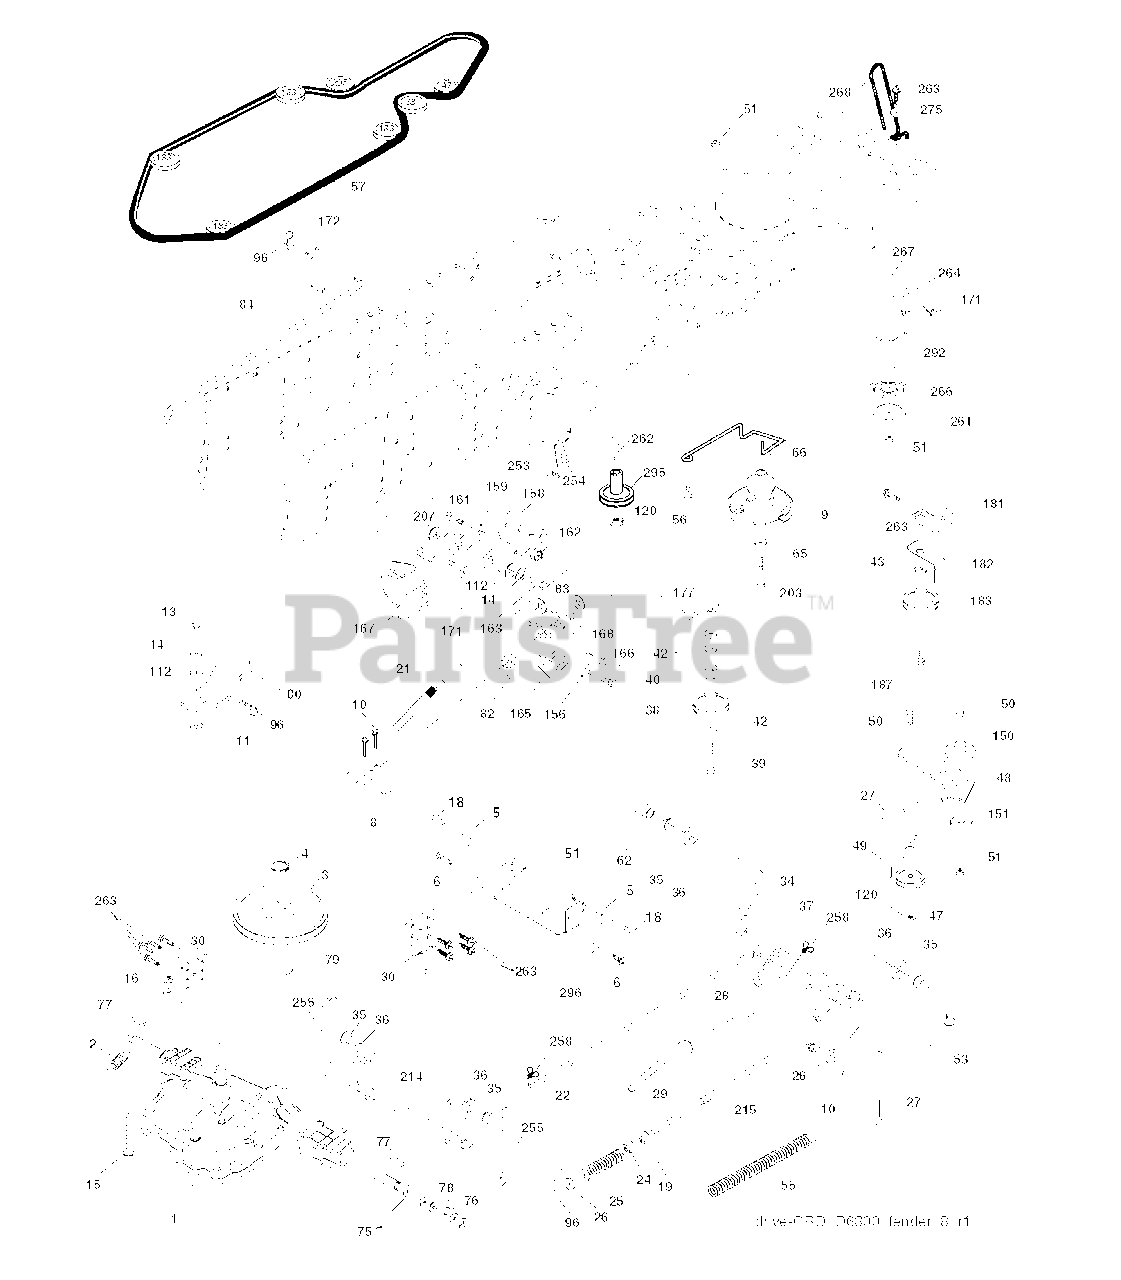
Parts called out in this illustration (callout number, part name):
2	SPRING,BRAKE RETURN
4	RETAINING RING LT
5	STRAP TORQUE
6	SCREW 5/16"
8	ROD SHIFT FENDER ADJUST LT
10	PIN COTTER
11	WASH-SHFT PLT LT
13	BOLT 1/4-28X3/4
14	LOCKWASHER
15	BOLT HEX 5/16-18 GR 5
16	NUT.71038.31-18.HEX.NYLOCK
19	NUT
21	KNOB T (1/2-HOLE)
24	NUT
25	SPRING ROD LT
27	COTTER PIN
28	ROD, PARKING BRAKE
29	PLUNGER CAP
30	BRKT, MOUNT TRNSAXLE
34	SHAFT, FOOT PEDAL
35	BEARING.NYLON
36	WASHER LT
37	DRIVE PIN
38	PULLEY.FLAT
42	WASHER
47	IDLER PULLEY
48	BELLCRANK, CLUTCH
49	RETAIN BELT
50	BOLT.3/8-16X1.50
51	LOCKNUT
53	LINK.CLUTCH.7.66.2005
55	SPRING, RETURN LT
56	SCREW.3/8-16
62	PEDAL COVER T
65	LOCKWASHER
66	KEEPER BELT ENGINE
76	E-RING LT
77	SQUARE KEY
80	ARM SHIFT
82	SHIFT SPRING
83	WASHER
96	RETAINER M
112	WASHER LT
120	NUT LOCK FLG 3/8-16 UNC
150	BUSHING.BELLCRANK.GRD.DR
151	WASHER 12/32X2X10GA
156	WASHER.SRRTD.5/16
158	BRACKET
159	HUB.SHIFT
161	BOLT
162	NUT.CROWNLOCK.1/4
165	RP BRACKET
167	BRACKET
168	BOLT.SHOULDER.5/16-18X
187	BOLT.5/16-18X1.25
207	WASHER NYL
254	SCREW 3/8-16X1
258	CLIP RETAINER
261	FLAT IDLER PULLEY
263	SCREW, 3/8-16X3/4
275	WASHER
295	PULLEY IDLER COMPOSITE
